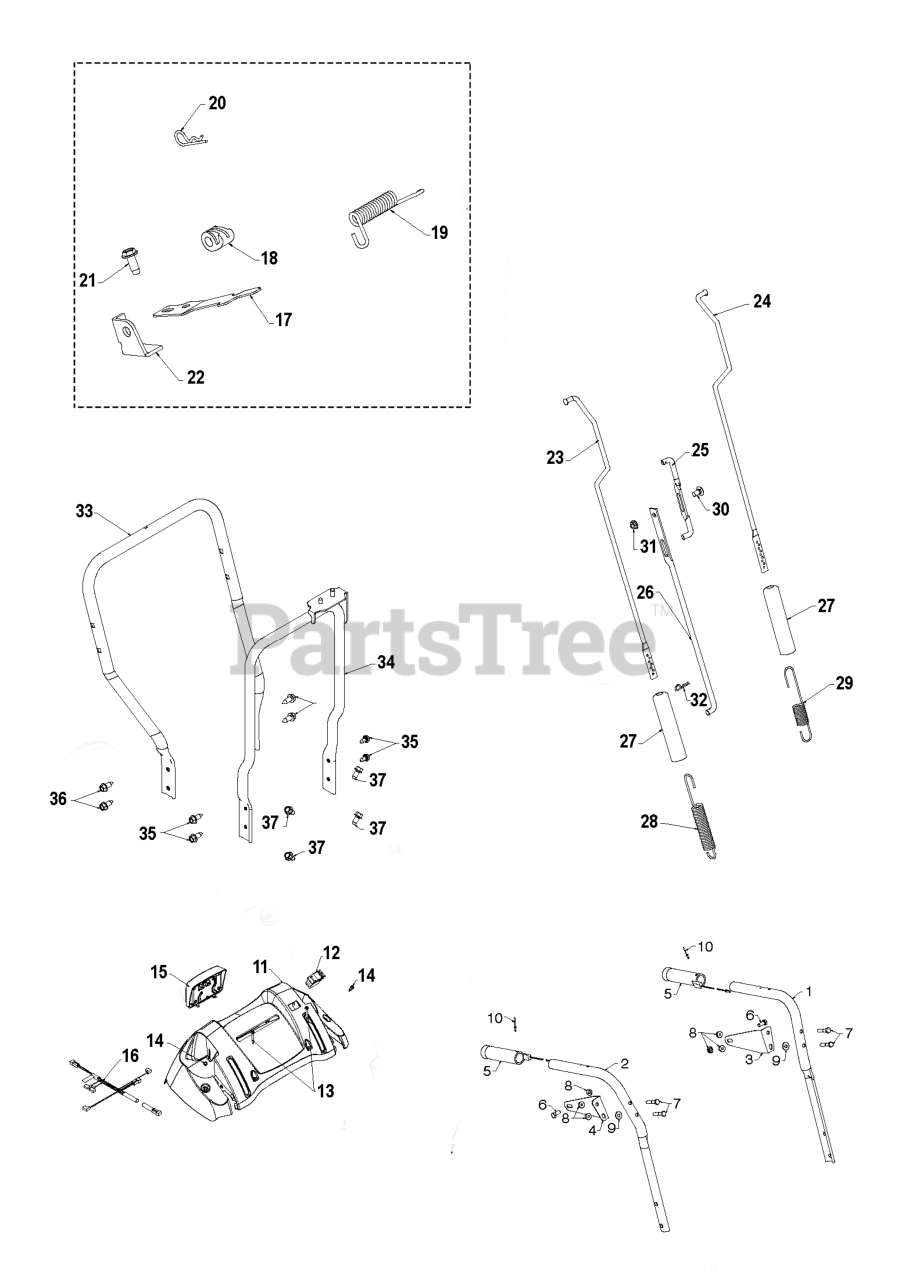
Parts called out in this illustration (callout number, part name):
1	TUBE.HANDLE.PLOW.LH.GREY
2	TUBE.HANDLE.PLOW.RH.GREY
3	BRACKET.PANEL.LH.
4	BRACKET.PANEL.RH.
5	GRIP.HANDLE.HEATED
6	BOLT.FIN.HEX.5/16-18X3/4
7	HEX BOLT
8	NUT.LOCK.5/16-18
9	WASHER.20X8.5
10	RIVET.POP.1/8X
11	PANEL.CONSOLE.
12	SWITCH.HEATED.GRIP
13	SCREW, HEX HD TAPPING #10-24 1
14	SCREW, HEX HEAD, TAPPING
15	HEADLIGHT.LED.DUAL STAGE.GREY
16	HARNESS.WIRE.FLOOD/LED.HEAT.
17	SPRING.INTERLOCK
18	CAM.INTERLOCK.RELEASE
19	SPRING.TORSION.LEVER
20	SPRING RETAINER
21	SCREW 14-20 X 5/8
22	STOP.INTERTLOCK
23	ROD.IMPELLER
24	ROD.TRACTION
25	ROD.SHIFTER.TOP.HYD
26	ROD, LOWER, SPEED CONTROL
27	SLEEVE, SPRING
28	SPRING.CONTROL.ROD.SNOW
29	SPRING.TRACTION.ROD.SNOW
30	BOLT
31	NUT.FLANGE.5/16
32	SPRING RETAINER
33	HANDLE.LOWER.CHAIN.SNOW.GREY
34	SUPPORT.WELDMENT.ROTATOR.BLACK
35	BOLT.5/16HEX.WHS.HD
36	SCREW 3/8-16X1
37	SCREW, 3/8-16X3/4
